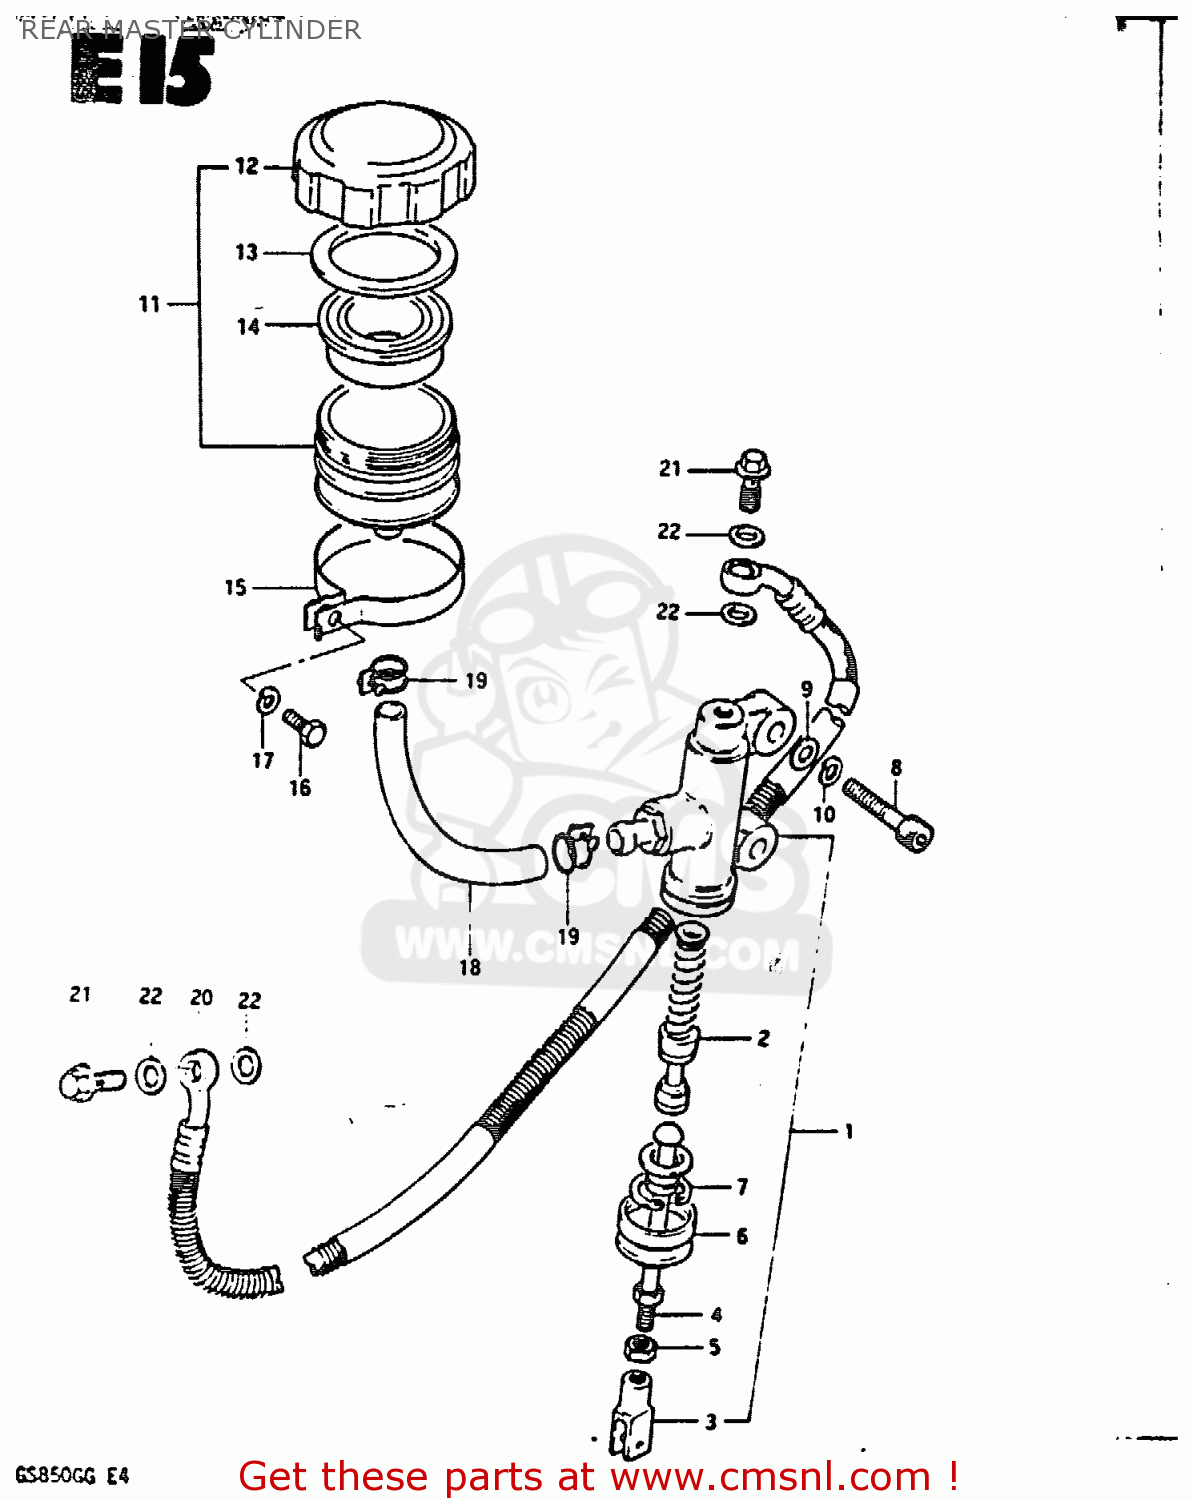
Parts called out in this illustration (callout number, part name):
1	CYLINDER ASSY,RR MASTER
2	PISTON/CUP SET
3	YOKE
4	ROD,REAR MASTER CYLINDER
5	NUT,MASTER CYLINDER
6	BOOT
7	CIRCLIP
8	BOLT, REAR (8X30)
9	WASHER
10	LOCK WASHER
11	RESERVOIR TANK ASSY
12	CAP
13	PLATE,DIAPHRAGM
14	DIAPHRAGM
15	CLAMP
16	BOLT, UPPER
17	WASHER,LOCK
18	HOSE,RESERVOIR TANK
19	CLAMP
20	HOSE,REAR BRAKE
21	BOLT UNION
22	WASHER(10X15X1.5)
